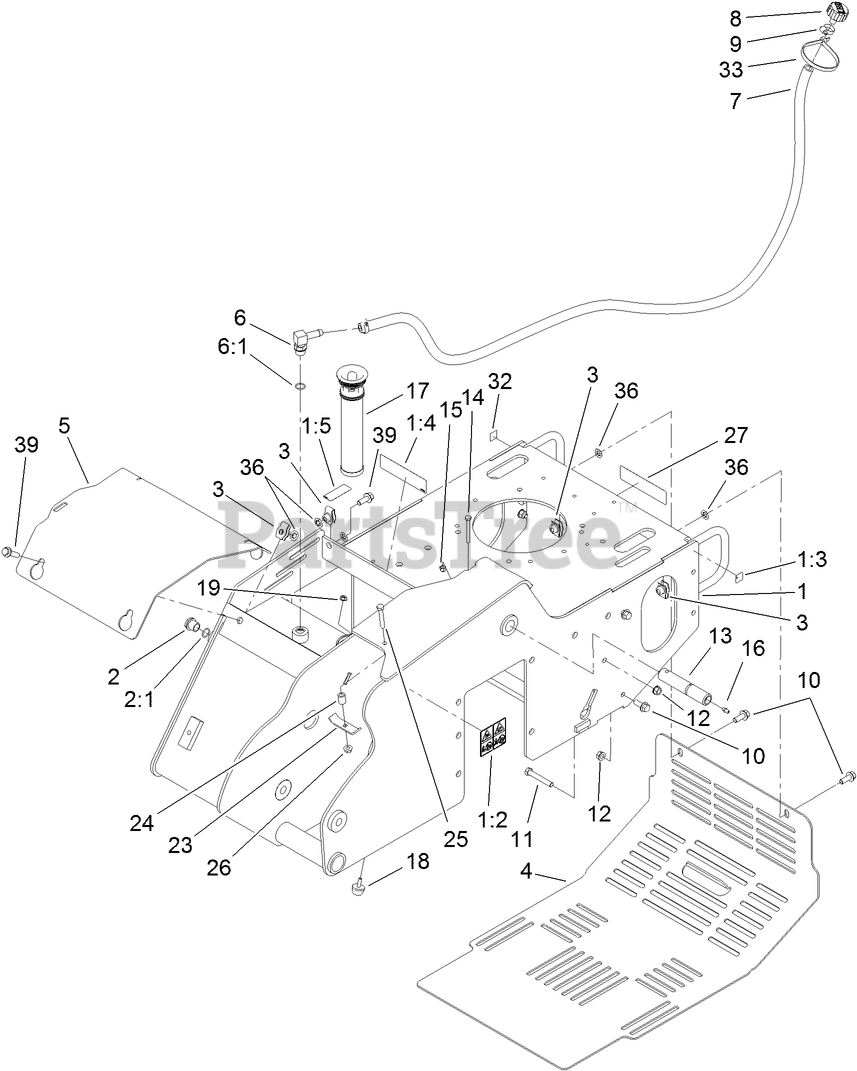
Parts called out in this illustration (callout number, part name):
1	MAIN FRAME ASM
1:2	DECAL-WARNING
1:3	DECAL-POINT, LIFT
1:4	DECAL-DANGER
1:5	DECAL-OIL, HYD
2	SIGHT GLASS ASM
2:1	O-RING
3	NUT-CLIP, U
4	COVER-REAR
5	PLATE-COVER, FRONT
6	FITTING-ELB 90
6:1	O-RING
7	HOSE-BREATHER
8	BREATHER
9	CLAMP-HOSE
10	SCREW-HHF
11	SCREW-HH
12	NUT-FLANGE
13	PIN-PIVOT
14	SCREW-HH
15	NUT-LOCK, NI
16	FITTING-GREASE
17	IN-TANK FILTER ASM
18	BUMPER
19	NUT-HF
23	BRACKET-CLAMP
24	SPACER
25	SCREW-HH
26	NUT-HF
27	DECAL-DANGER
32	DECAL-POINT, LIFT
33	TIE-CABLE
36	NUT-PUSH
39	SCREW-HHF
